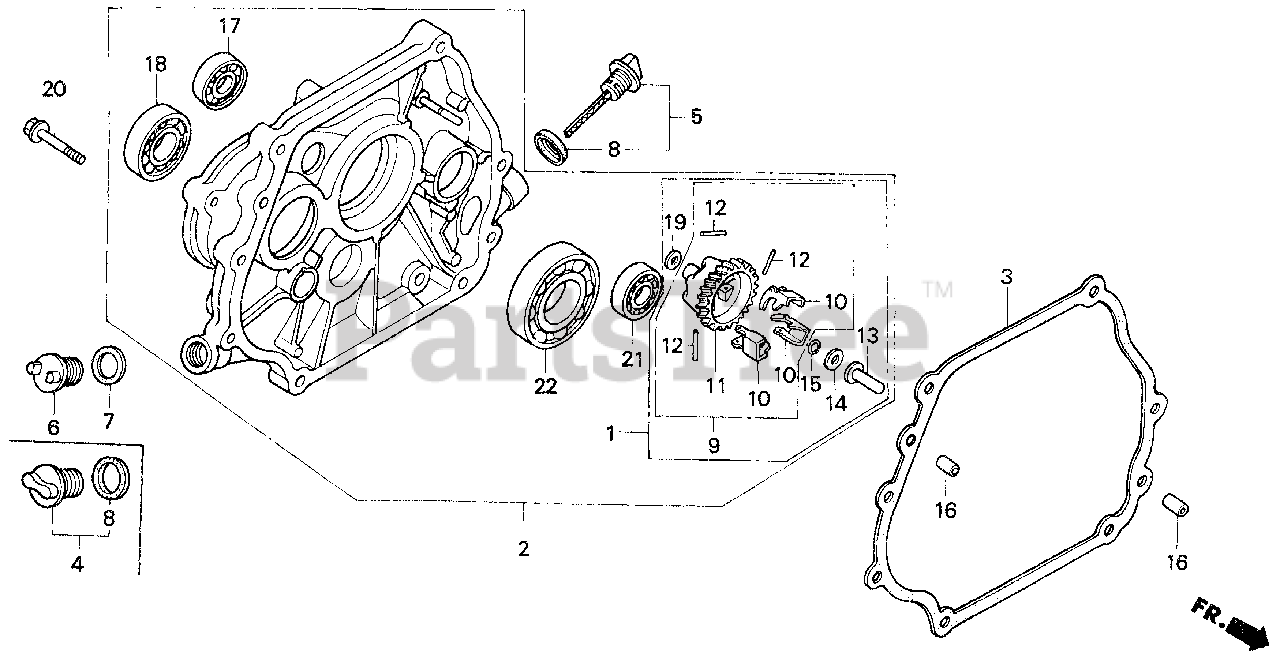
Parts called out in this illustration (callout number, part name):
1	GOVERNOR KIT
2	COVER ASSY., CRANKCASE
3	GASKET, CASE COVER
4	CAP ASSY., OIL FILLER
5	CAP ASSY., OIL FILLER
6	CAP, OIL FILLER
7	GASKET, OIL FILLER CAP
8	GASKET, OIL FILLER CAP
9	GOVERNOR ASSY.
10	WEIGHT, GOVERNOR
11	HOLDER, GOVERNOR WEIGHT
12	PIN, GOVERNOR WEIGHT
13	SLIDER, GOVERNOR
14	WASHER (6X16)
15	CLIP, GOVERNOR HOLDER
16	PIN, DOWEL (8X12)
17	BEARING, RADIAL BALL (6202)
18	BEARING, RADIAL BALL (6204) (TOYO)
19	WASHER, PLAIN (6MM)
20	BOLT, FLANGE (8X40)
21	BEARING, RADIAL BALL (6202)
22	BEARING, RADIAL BALL (6207)
